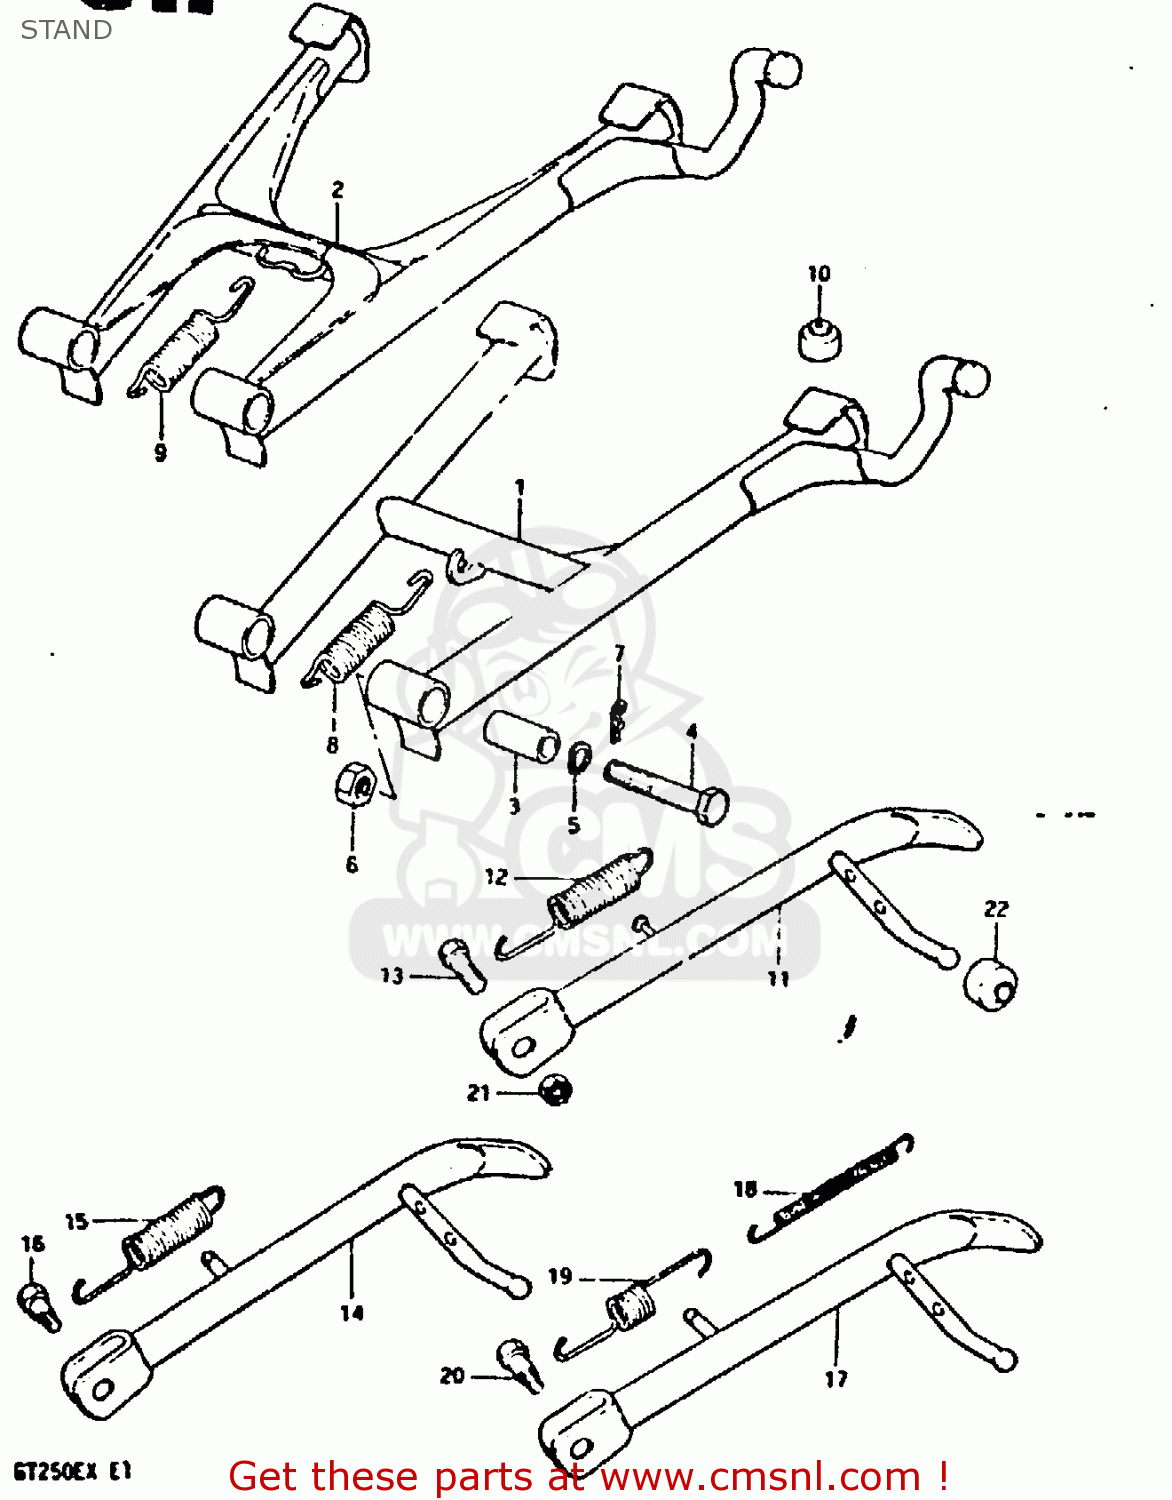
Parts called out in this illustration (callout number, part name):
1	STAND, CENTER
3	SPACER(10X16X38.8)
4	BOLT
5	LOCK WASHER
6	NUT
7	CLIP
8	SPRING
10	CUSHION
11	STAND, PROP
12	SPRING
13	BOLT(10X30)
21	NUT
22	CUSHION
